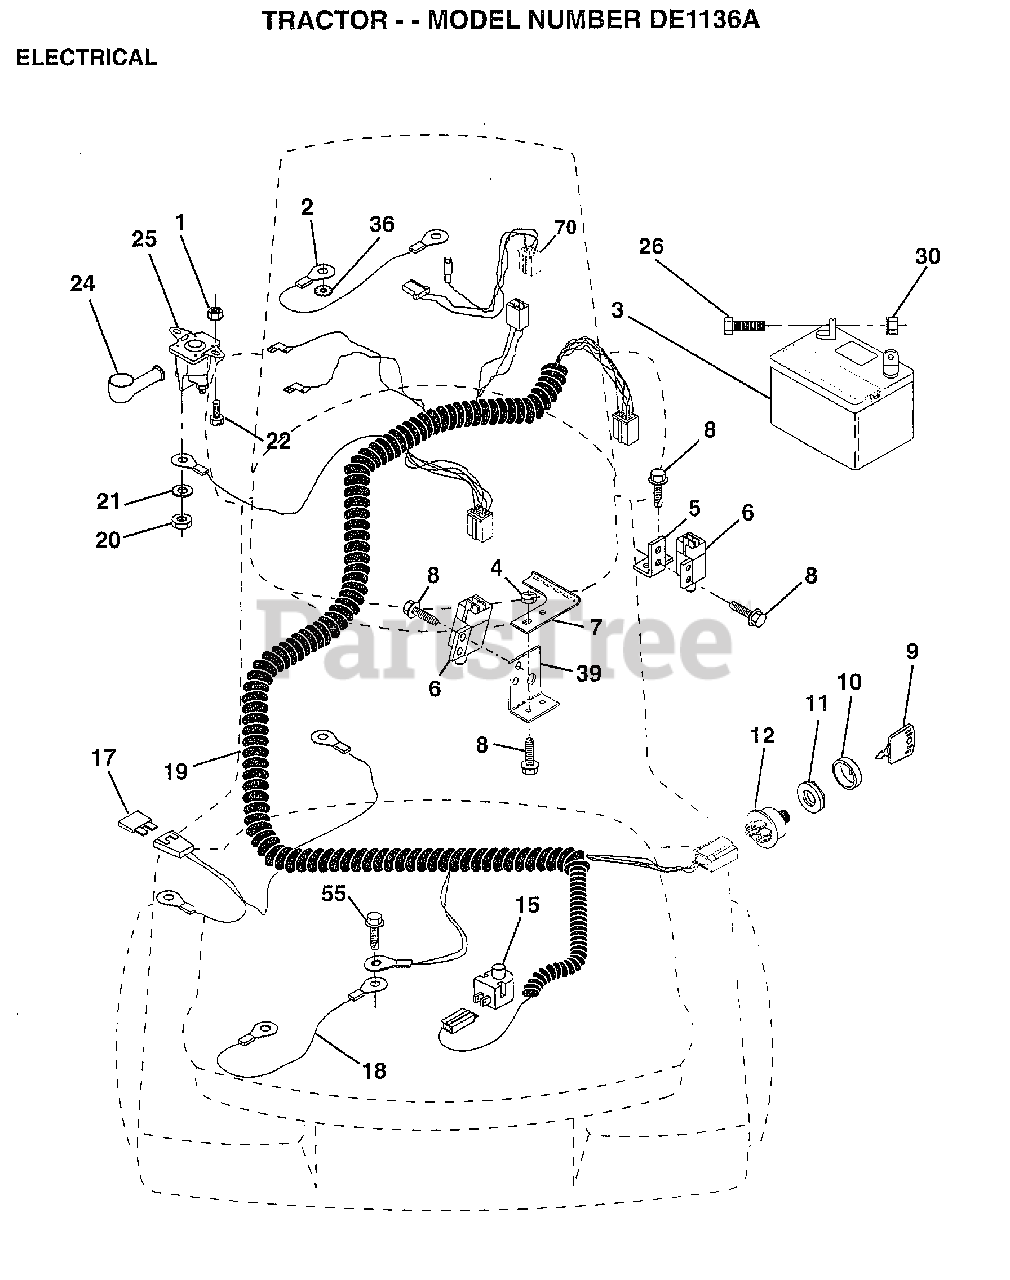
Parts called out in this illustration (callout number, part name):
1	NUT HXKEP 1/4X20
2	CABLE ASM.
4	LOCKNUT
5	BRACKET LT
6	SWITCH INTERLOCKT
7	KEEPER.ACTUAT.LR.
8	SCREW
9	KEY STEEL DELTA
10	COVER KEY SWITCH
12	SWITCH.IGNITION
15	SWITCH SEAT
17	FUSE HYT
18	CABLE ASSY
19	HARNESS.IGNITION
20	NUT
22	BOLT HXHD FIN
26	BOLT LT
30	NUT
36	LOCKWASHER
39	BRACKET SWT CLUTC
55	SCREW LT
70	HARNESS.ENGINE
